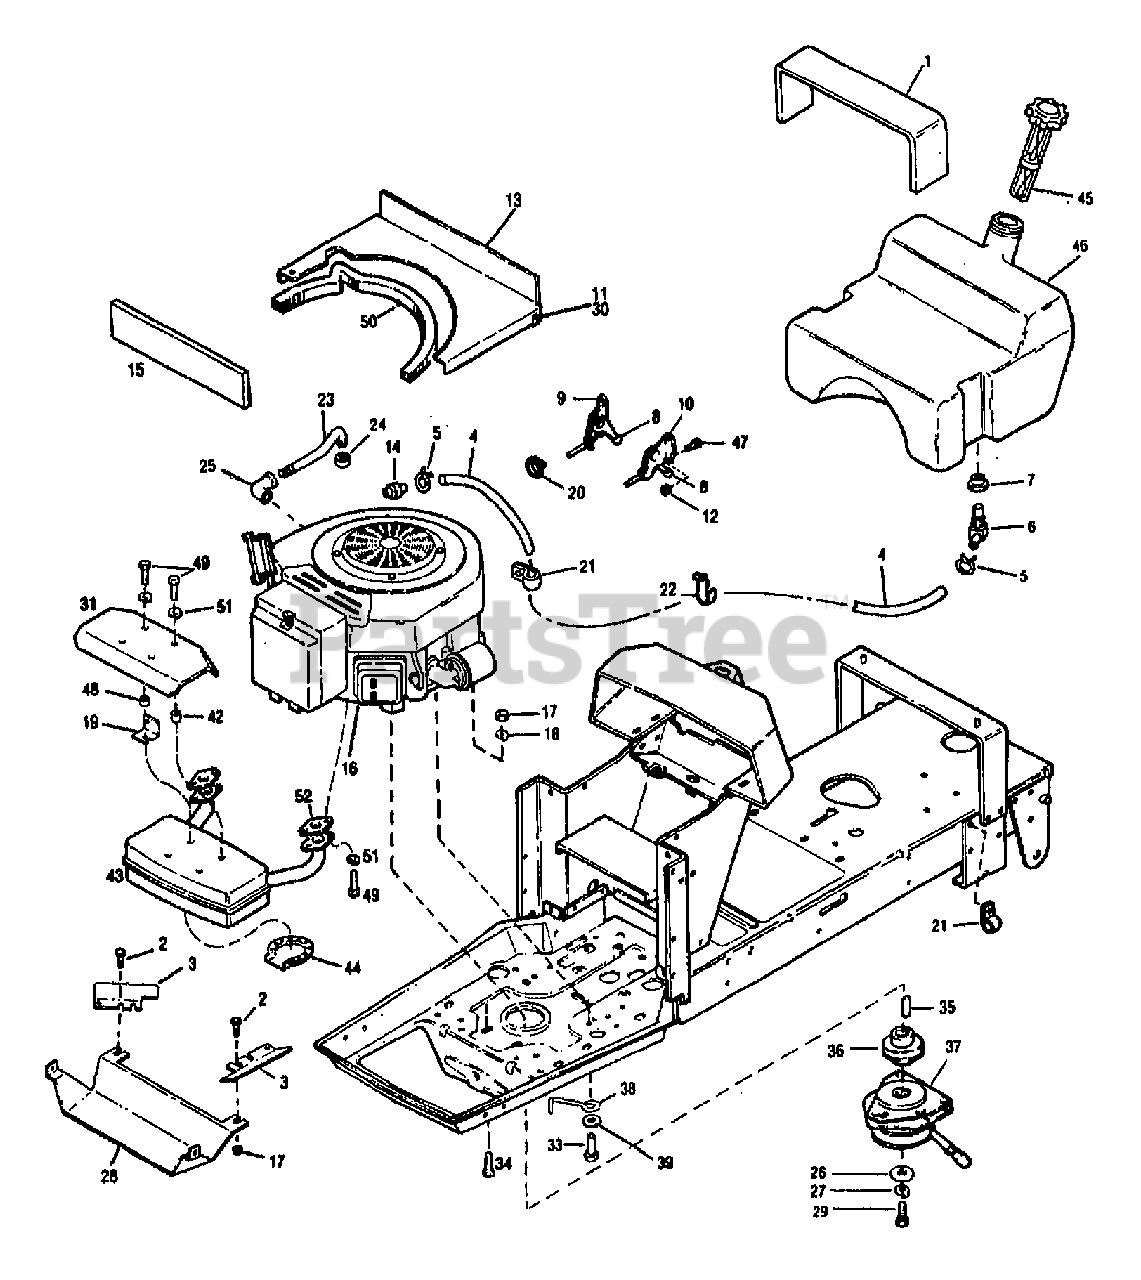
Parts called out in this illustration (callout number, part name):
1	PAD-FUEL TANK
2	SCR-HFLK 5/16-18X.75 ZP
3	SHIELD-HEAT
4	FUEL LINE
5	CLAMP-HOSE
6	ELBOW-90 DEG (FUEL LINE)
7	BUSHING-RUBBER
8	KNOB
9	CONTROL-THROTTLE
10	CONTROL-CHOKE
11	SCR-TRUSS #10-24 X 5/8
12	NUT W/LKWASHER 10-24 ZP
13	SHIELD-HEAT
14	FILTER-FUEL
15	FOAM-LOWER
16	ENGINE, B&S 14HP MODEL 294777 {13065}
16	ENGINE, B&S 16HP MODEL 303777 {13066}
17	NUT-HEX 5/16-18 ZP
18	WASHER-LK .312 ZP
19	BRKT-HEAT SHIELD
20	TIE-CABLE NYLON BLACK
21	CLIP-J
22	HANGER-CABLE
23	TUBE-OIL DRAIN
24	CAP-DRAIN TUBE
25	ELBOW-90 DEG (OIL DRAIN)
26	WASHER-SPEC 1.42X.468X.25 ZP
27	WASHER-LK .438 ZP
28	SHIELD-HEAT
29	SCR-HH 7/16-20X3.00
30	NUT-SPEED #10
31	SHIELD-HEAT
33	SCR-HH 5/16-18X2.00
34	SCR-HH 5/16-18X1.5 G5 ZP
35	KEY-.25 SQ X 2.5
37	CLUTCH-ELECTRIC
38	CLUTCH-RETAINER
39	WASHER-FLAT 5/16 SAE
44	DEFLECTOR-MUFFLER
45	CAP-GAS
46	TANK-FUEL
48	SPACER-.5X.281X.375
49	SCR-HH 1/4-20X1.0
50	STRIP-SEALING
51	WASHER-LK .25 ZP
52	GASKET
